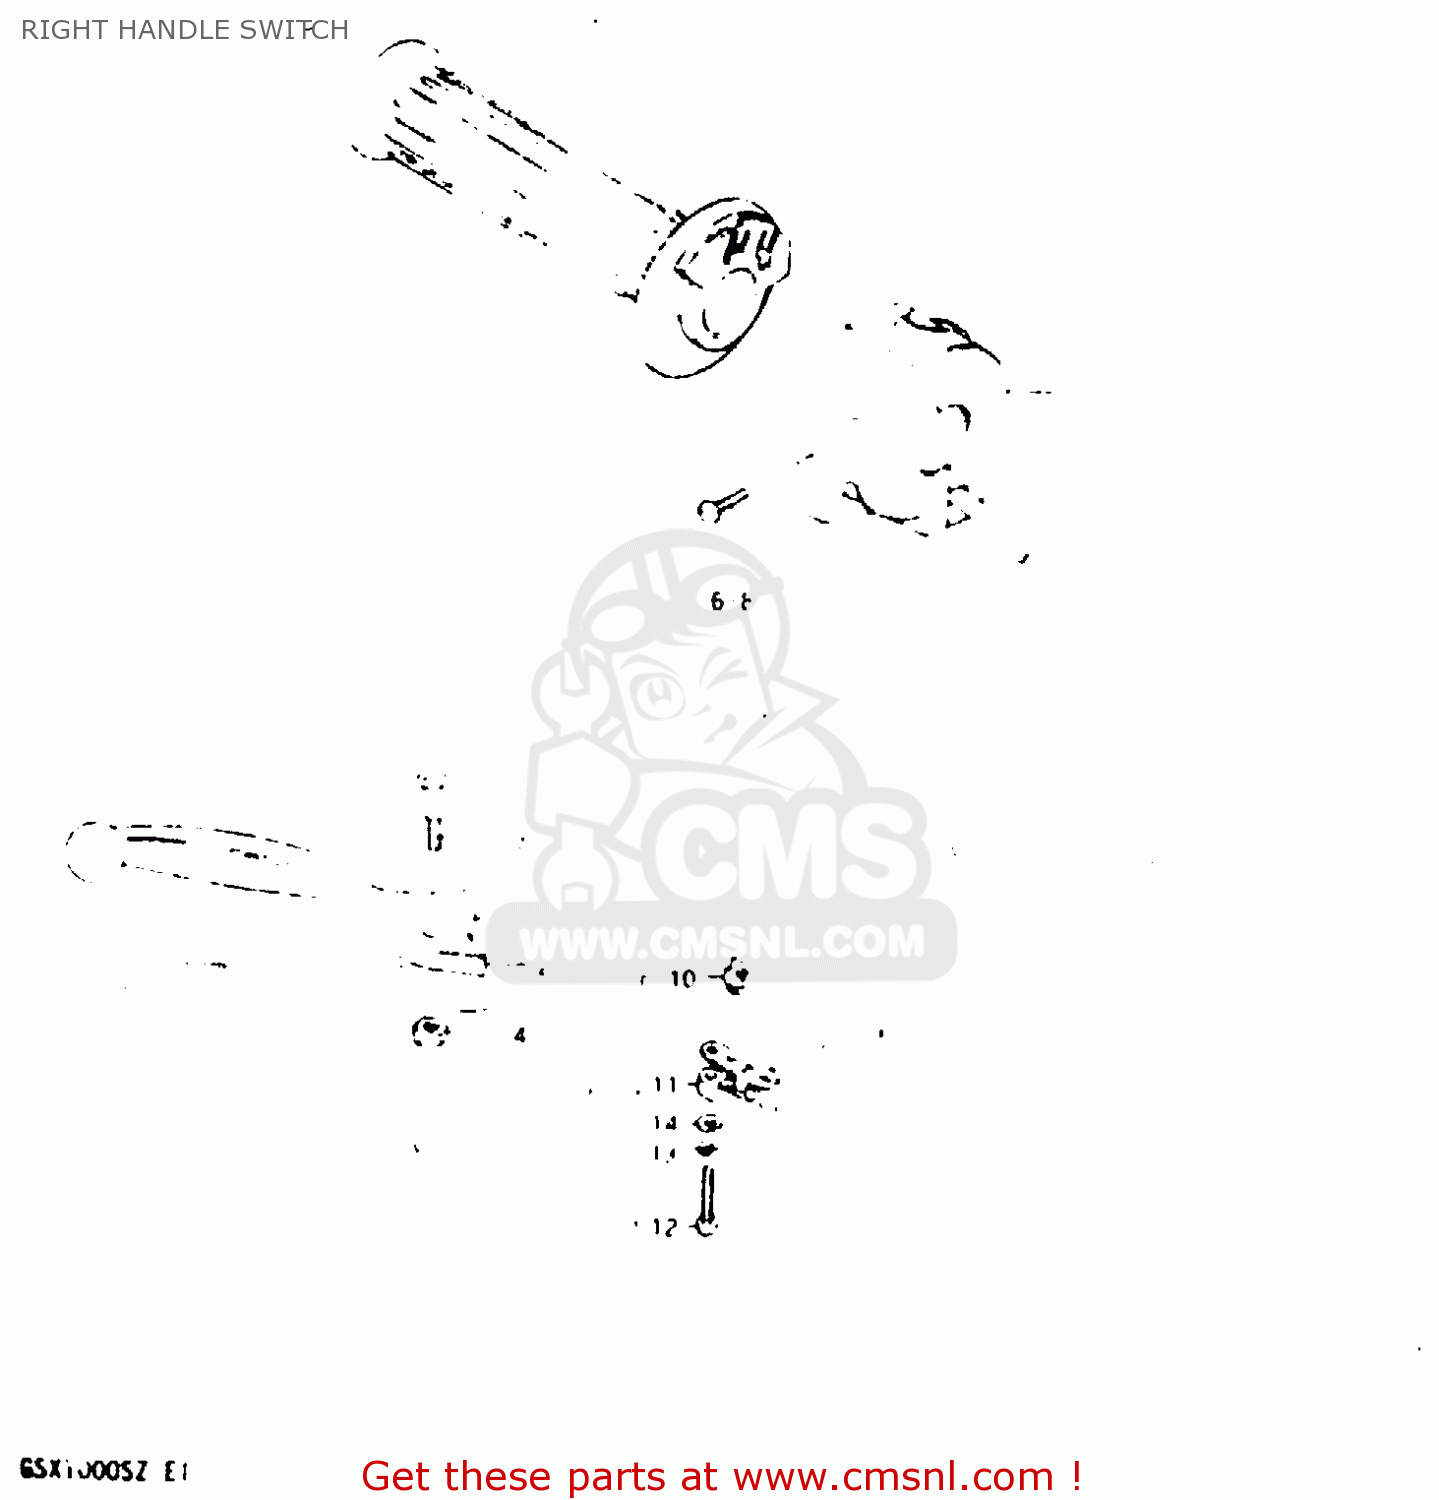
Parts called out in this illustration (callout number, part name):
1	GRIP, THROTTLE
2	LEVER,BRAKE
3	BOLT
4	NUT 6MM
5	SWITCH ASSY, HANDLE RH
6	SCREW
